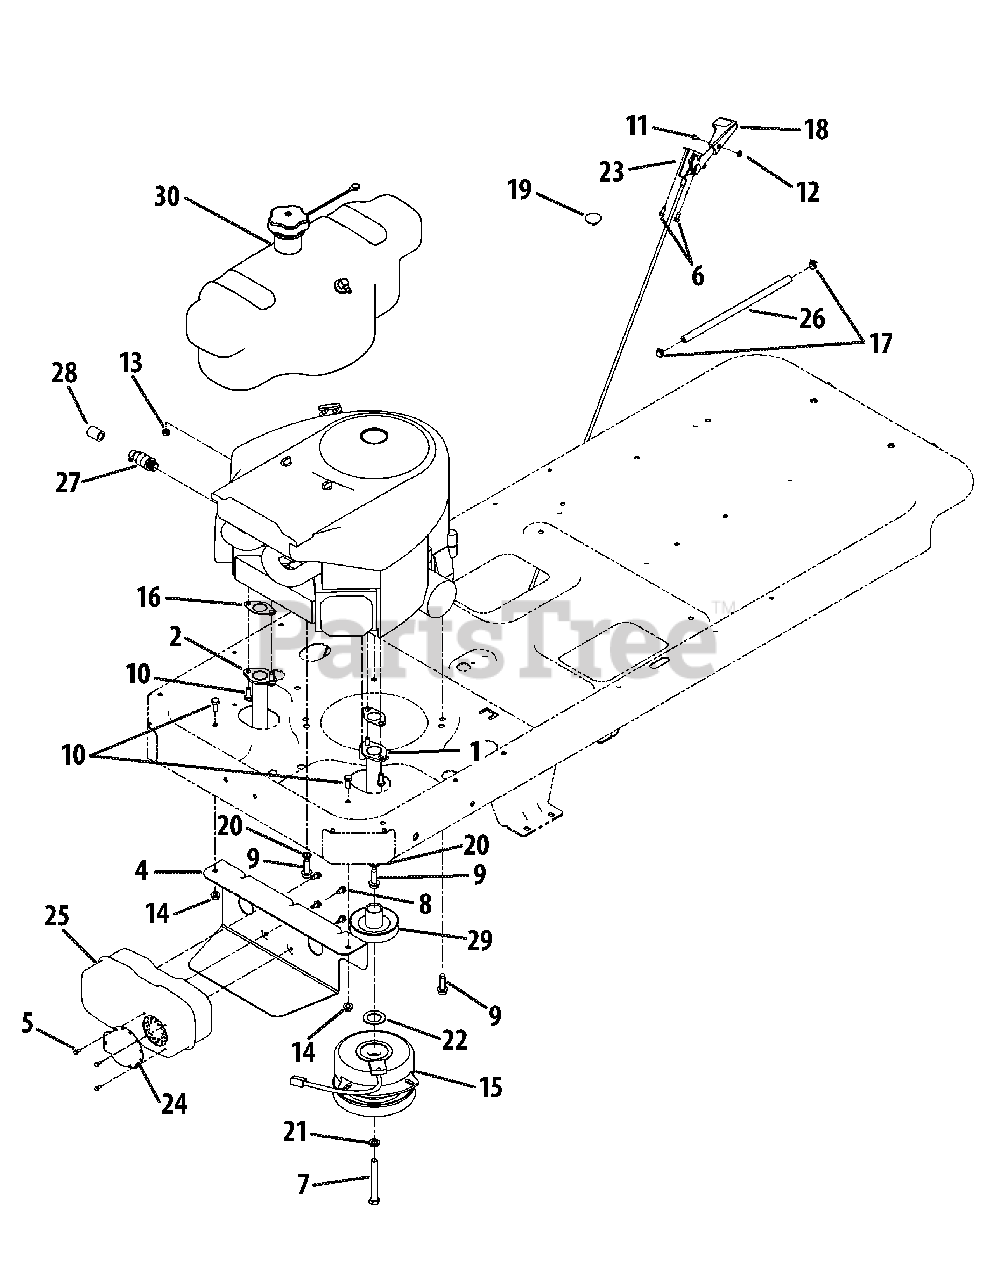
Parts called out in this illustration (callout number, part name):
1	Muffler Exhaust Tube, RH
2	Muffler Exhaust Tube, LH
3	Frame Assembly
4	Muffler Mount Bracket
5	Hex Washer Screw, #8-18 x .500
6	Hex Washer Screw, #12-16 x .50
7	Hex Lock Screw, 7/16-20 x 3.50
8	Hex Washer Screw, 1/4-20 x .500
9	Hex Washer Screw, 3/8-16 x 1.000
10	Hex Screw, 5/16-18 x .75
11	Machine Screw, #8-32 x .375
12	Hex Nut, #8-32
13	Sems Nut, 1/4-20
14	Flange Lock Nut, 5/16-18
15	Electric PTO Clutch
16	Exhaust Gasket
17	Hose Clamp
18	Throttle Control Knob
19	Choke Plug
20	Lock Washer, 3/8
21	Lock Washer, 7/16
22	Flat Washer, 1.031 x 1.620 x .095
23	Throttle/Choke Control Cable
24	Muffler Deflector
25	Muffler
28	Oil Drain Extension Hose
29	PTO Pulley
30	Fuel Tank Assembly
30	Fuel Tank
